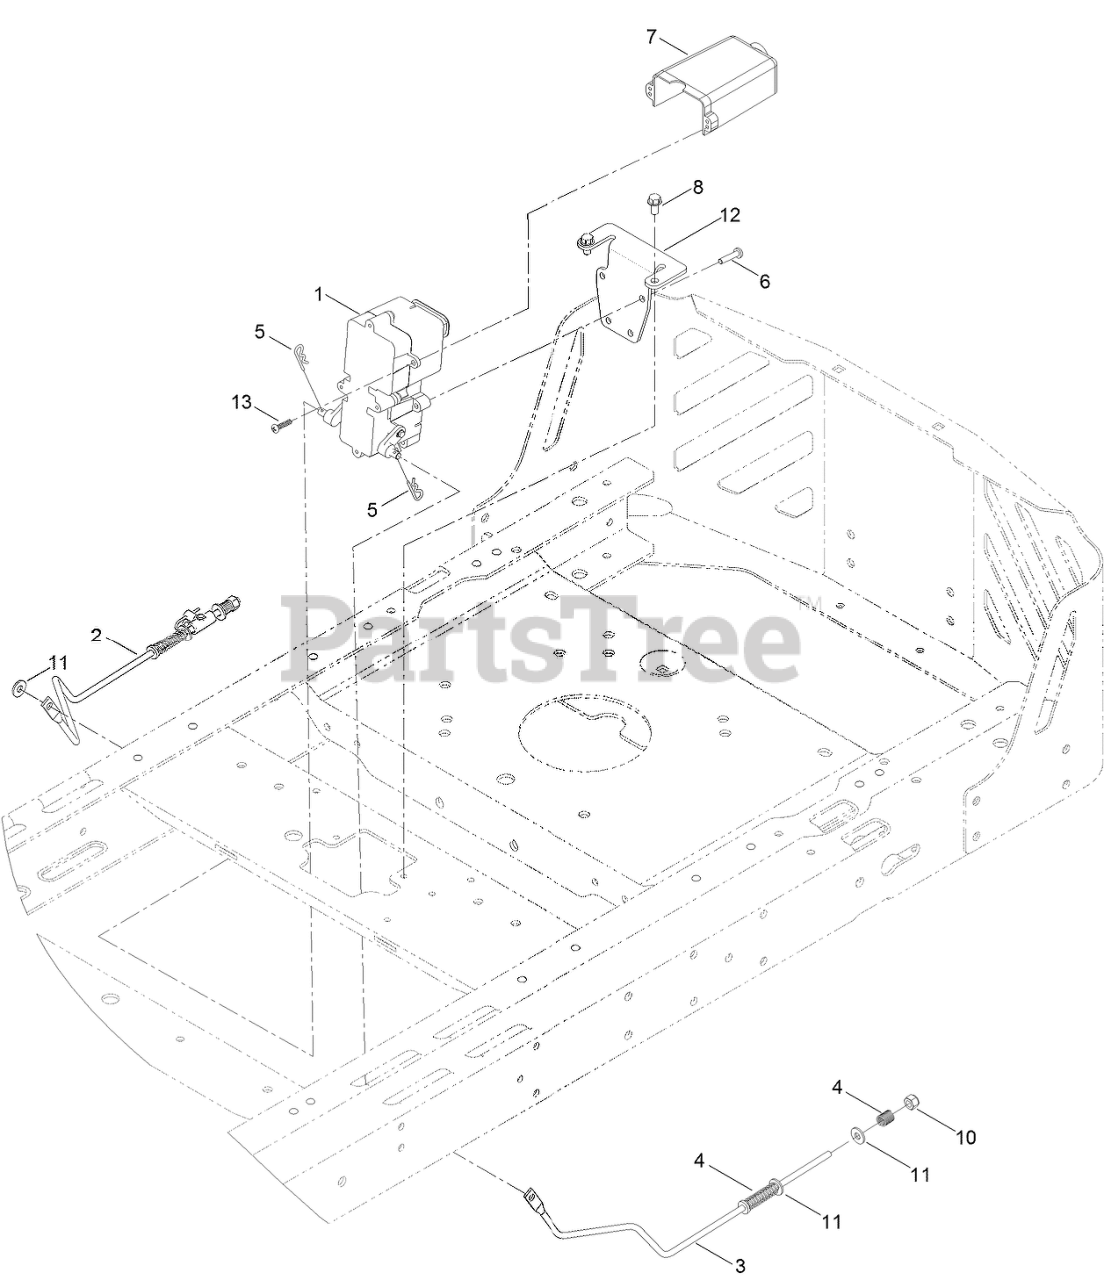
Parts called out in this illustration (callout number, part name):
1	BRAKE BOX ASM
2	ROD-BRAKE, RH
3	ROD-BRAKE, LH
4	SPRING-COMPRESSION
5	PIN-COTTER
6	SCREW-PPH
7	COVER-CONNECTOR
8	SCREW-HWH
10	NUT-LOCK, NI
11	WASHER
12	BRACKET-MOUNT, BRAKE
13	SCREW-PPH
